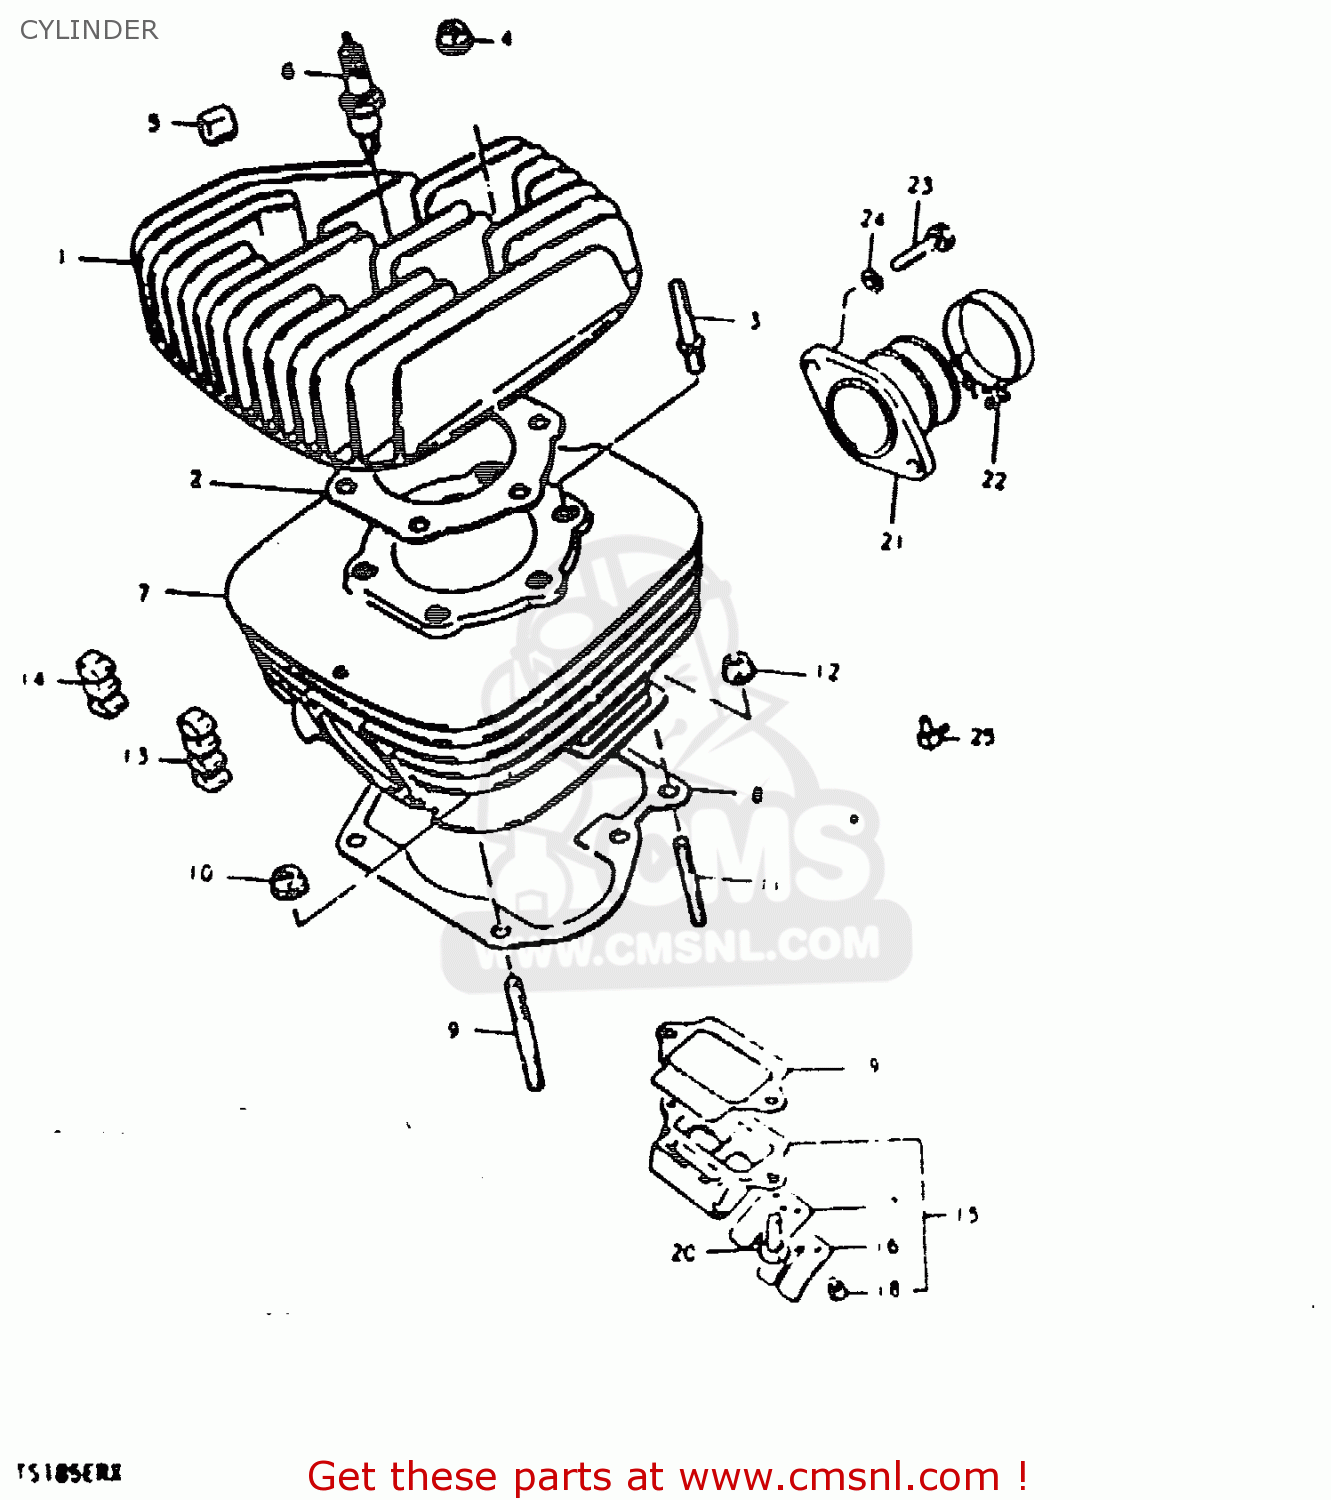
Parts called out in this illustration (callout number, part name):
1	HEAD,CYLINDER
2	GASKET,CYLINDER HEAD (NAS)
3	BOLT,STUD
4	NUT
5	PAD,CYLINDER
6	SPARK PLUG
7	CYLINDER
8	GASKET,CYLINDER (MCA)
9	STUD 10X25
10	NUT
11	STUD 8X25
12	NUT
13	PAD,CYLINDER
14	PAD,CYLINDER
15	VALVE ASSY,REED
16	STOPPER,REED VALVE
17	VALVE,REED
18	SCREW,REED VALVE
19	GASKET,REED VALVE (MCA)
20	SCREW
21	PIPE,INTAKE
22	CLAMP
23	BOLT, UPPER
24	LOCK WASHER
25	UNION,OIL HOSE
